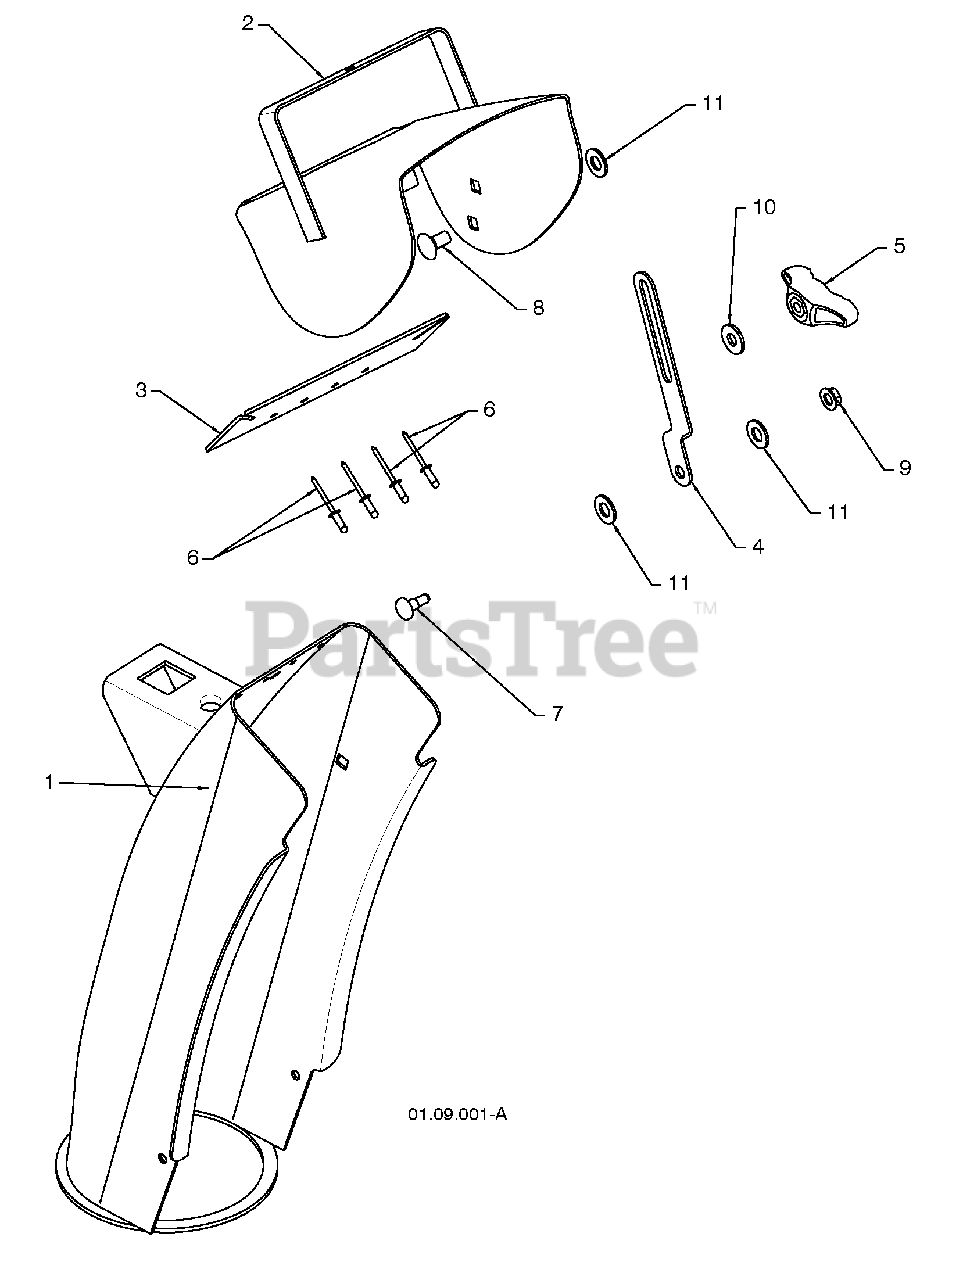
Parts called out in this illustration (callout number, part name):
1	CHUTE WELDMENT
2	DEFLECTOR WELDMENT
3	DEFLECTOR SEAL
4	STRAP
5	KNOB BLACK
6	POP RIVET
7	SHOULDER BOLT 1/4-20 X .704
8	CARRIAGE BOLT 5/16-18 X .625
9	NUT 1/4-20
10	WASHER
11	PLASTIC WASHER
